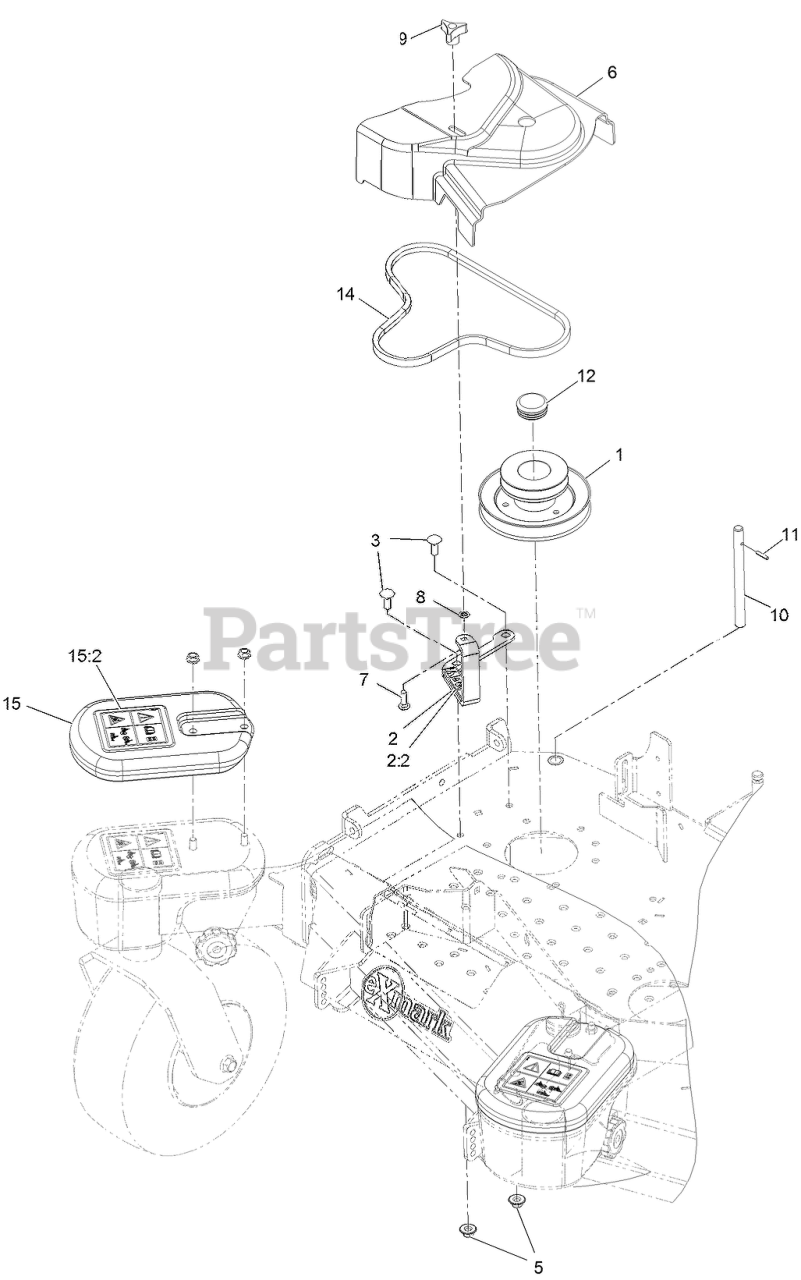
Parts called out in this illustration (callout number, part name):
1	JACKSHAFT- UV DRIVE 483
2	ASM-CVR BRKT W/DECAL
2:2	DECAL-DANGER
3	BOLT-CARR
5	Nut-Nyloc 3/8-16 Flg
6	COVER-BELT, UV 48
7	BOLT-CARR
8	RING-RETAINING, BOLT
9	KNOB-3 PRONG
10	SHAFT-CATCHER, GRASS
11	PIN-ROLL
12	PLUG-ROUND PLASTIC
14	BELT-BLOWER
15:2	DECAL-WARNING, TRACTION
